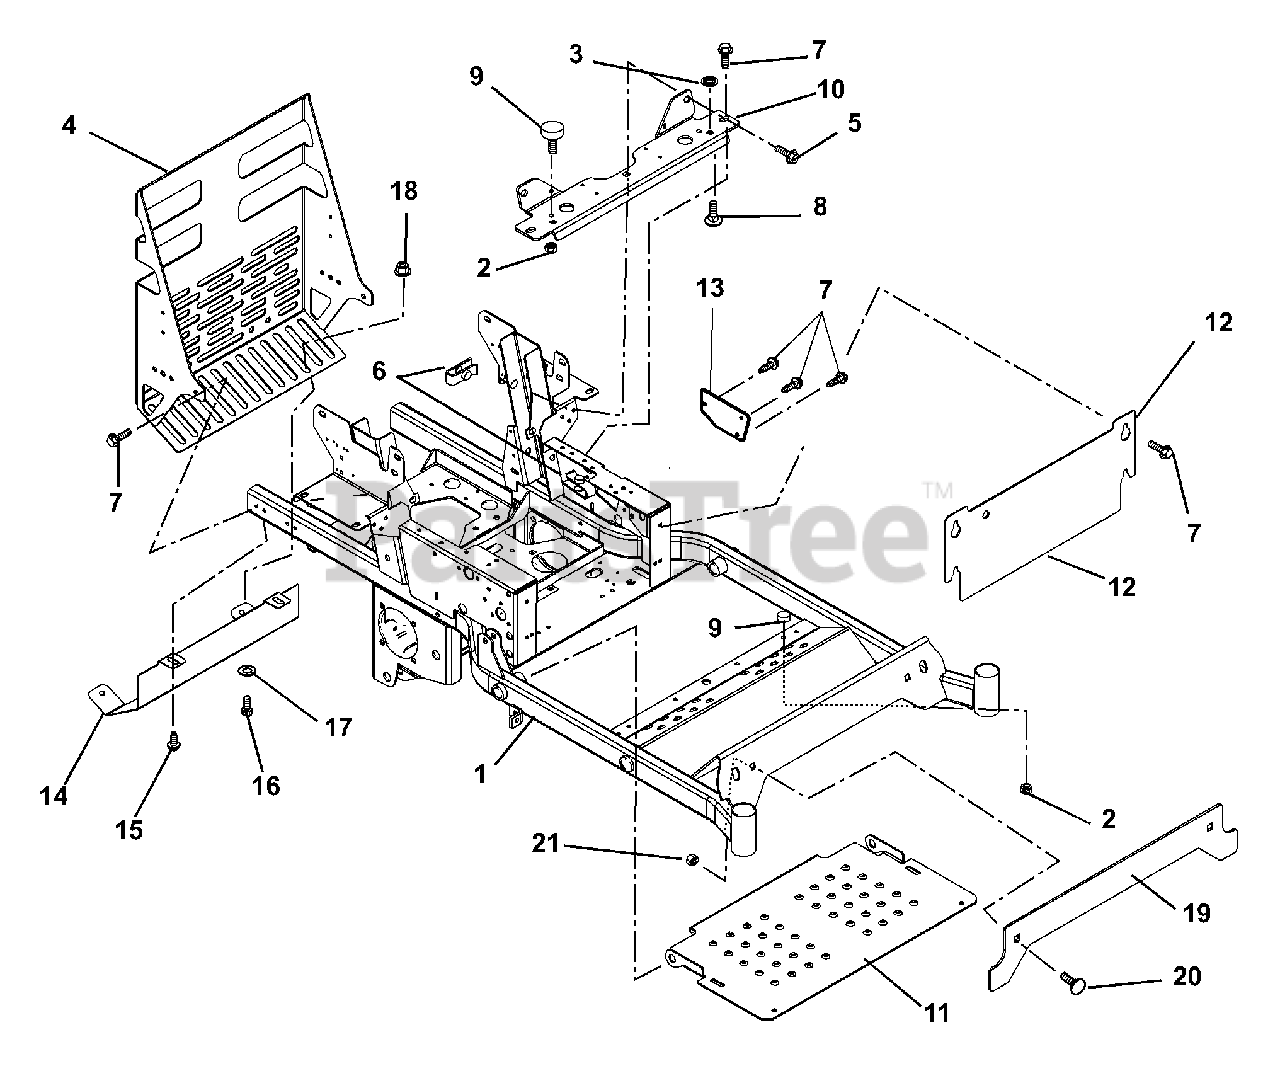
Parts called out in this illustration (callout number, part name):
1	Intermediate-Z Frame
2	Nut, Spin Lock Flange .312-18
3	Nut, Push .312
4	Bumper with Heat Shield
5	Bolt, Serrated Flange Washer Head .38-16 x 1.00
6	Nut, Retainer .375-16 x .37
7	Screw, Tapping Hex Washer Head .38-16 x .50
8	Bolt, Round Head Square Neck .31-18 x 1.00 Grade 5
9	Bumper, Rubber
10	Seat Support
11	Footrest Panel
12	Access Panel
13	Valve Cover
14	Heat Shield
15	Screw-Tapping .38-16 x .50 Hex Washer Head Thread Rolling YWZ
16	Bolt-Hex .38-16 x .75 Grade 5
17	Washer-Flat-Steel .438 x 1.00 x .083
18	Nut-Locking-Top-Flange .38-16
19	Plate, Counterweight
20	Bolt-Round Head Square Neck .50-13 x 1.75 Grade 5
21	Nut .50-13 Nyloc Flange
